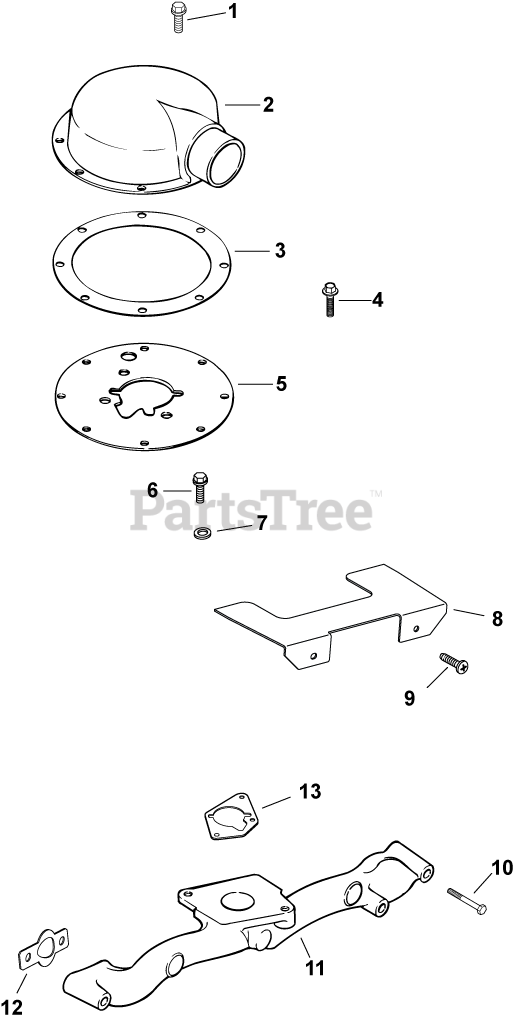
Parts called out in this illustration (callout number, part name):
1	SCREW,FLG THD FRM M6X1.0X16-(#25086397S)
2	KIT, HDAC IGLOO ADAPTER
3	GASKET, AIR CLEANER ADAPTER
4	SCREW, HVY FLG M5X.8X16
5	PLATE, ADAPTER-USE 24 029 83-S
6	SCREW, FLG M6X1.0X16
8	SHIELD, DEBRIS
9	SCREW, PHL HD 11-16X3/4"
10	SCREW, FLG M6X1.0X55
11	MANIFOLD, METAL INTAKE
12	GASKET, INTAKE MANIFOLD USE 24 041 79-S
13	GASKET, AIR CLEANER BASE
